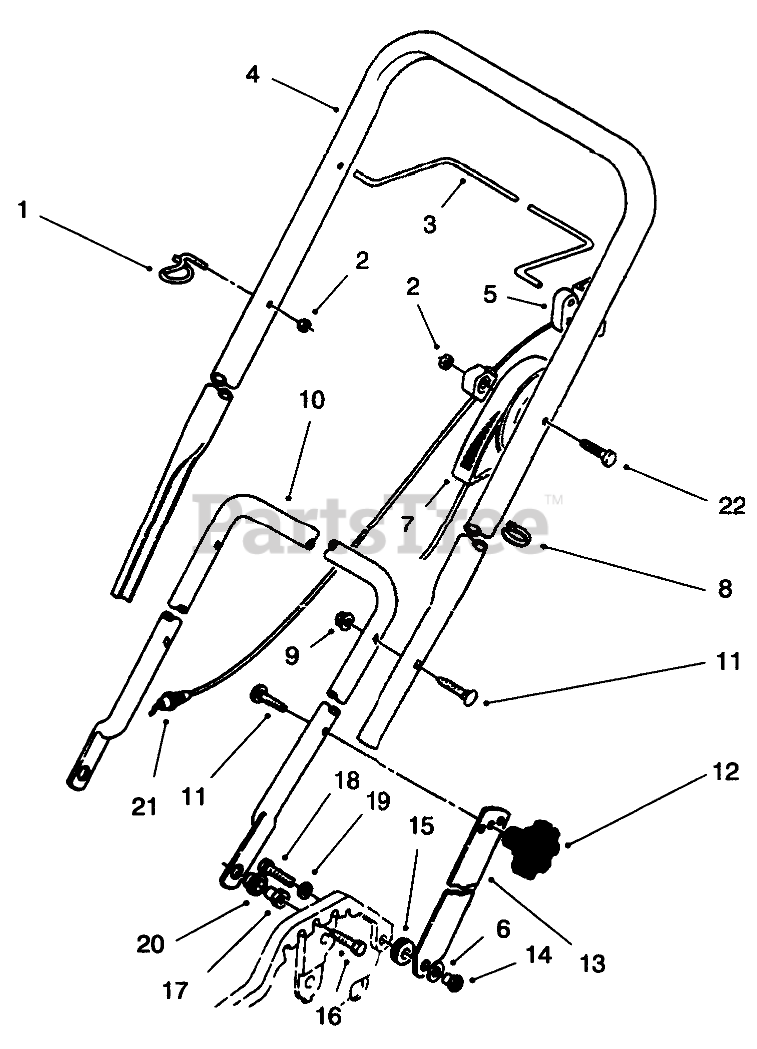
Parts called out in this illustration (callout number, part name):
1	GUIDE-ROPE
2	NUT-LOCK, NI
3	Bar-Control
4	UPPER HANDLE
5	STOP-PIVOT
6	WASHER
7	THROTTLE CABLE
8	TIE-CABLE
9	NUT-LOCK NI
10	LOWER HANDLE(CROM)
11	SCREW-HANDLE
13	HANDLE LATCH
14	POST-MOUNTING, LINKAGE
15	GROMMET
16	SCREW-HH
17	HANDLE PIVOT NUT
18	SCREW-HH
19	WASHER-LOCK
20	FLANGE BUSHING
21	BRAKE CABLE
22	SCREW-HH
